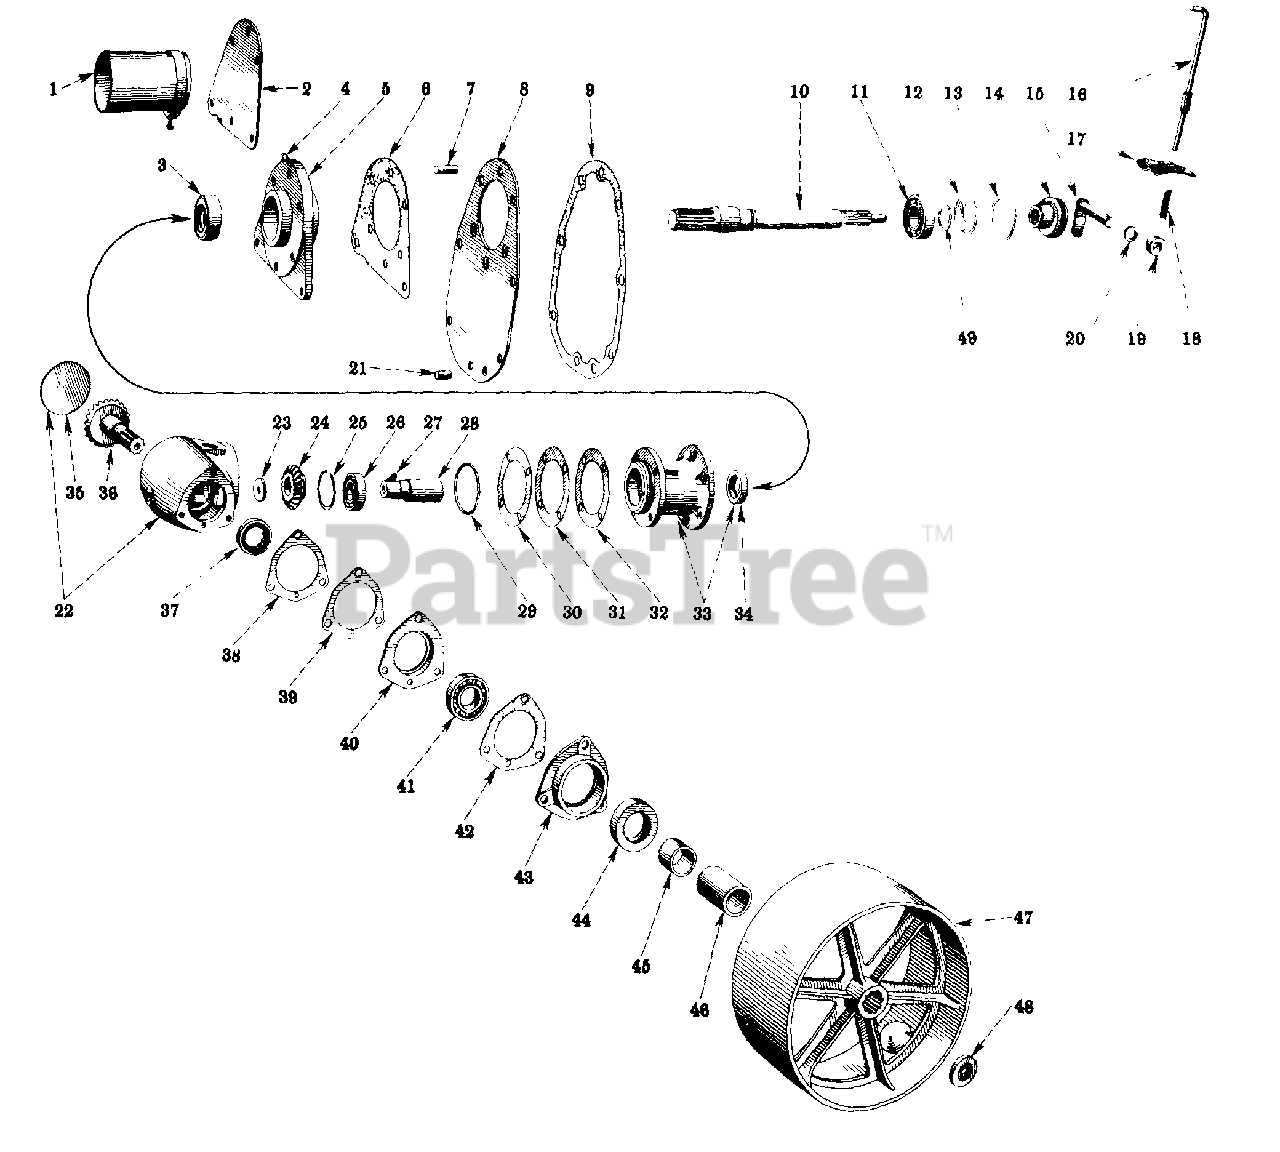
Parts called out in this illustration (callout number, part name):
1	GUARD ASSY, POWER TAKE OFF SHAFT
2	COVER, POWER TAKE-OFF ADAPTER
3	SEAL, POWER TAKE OFF SHAFT OIL
4	FITTING, 3/16 65 DEG. ANGLE DRIVE TYPE LUBRICATION
5	RETAINER ASSY. POWER TAKE-OFF SHAFT OIL SEAL AND BEARING
6	GASKET, POWER TAKE-OFF ADAPTER COVER
7	DOWEL, POWER TAKE-OFF ADAPTER UPPER
8	ADAPTER W/PRODUCT GRAPHIC, 539403-R1, POWER TAKE-OFF
9	GASKET POWER TAKE-OFF ADAPTER
10	SHAFT W/RING, 122791-R1 AND SHIELD, 351272-R2 PTO
11	BEARING, POWER TAKE-OFF SHAFT BALL
12	SHIELD, POWER TAKE-OFF BEARING GREASE
13	RING, POWER TAKE-OFF SHAFT BEARING SNAP
14	CLUTCH, POWER TAKE-OFF SHIFTER
15	LEVER AND SHAFT ASSY, POWER TAKE-OFF SHIFTER
16	ROD ASSY, POWER TAKE-OFF SHIFTER
17	GUIDE, POWER TAKE-OFF SHIFTER ROD
18	SPRING, POWER TAKE-OFF SHIFTER ROD
19	COLLAR, POWER TAKE-OFF SHIFTER LEVER
20	SEAL, POWER TAKE-OFF SHIFTER SHAFT
21	DOWEL, POWER TAKE-OFF ADAPTER LOWER
22	HOUSING ASSY, BELT PULLEY DRIVE
23	WASHER, BELT PULLY DRIVE PINION
24	PINION, BELT PULLEY DRIVE
25	RING, BELT PULLEY DRIVE HOUSING SUPPORT BEARING SNAP
26	BEARING, BELT PULLEY DRIVE HOUSING SUPPORT BALL
27	KEY, 3/16 X 3/4 WOODRUFF NO. 9
28	SLEEVE ASSY, BELT PULLY DRIVE PINION
29	O-RING, 2-3/4 X 3 X 1/8 BELT PULLEY DRIVE HOUSING
30	SHIM, BELT PULLEY DRIVE HOUSING
31	SHIM, BELT PULLEY DRIVE HOUSING
32	SHIM, BELT PULLEY DRIVE HOUSING
33	SUPPORT W/OIL SEAL, 19857D AND BREATHER, 355120-R91
34	SEAL, BELT PULLEY DRIVE HOUSING SUPPORT OIL
35	PLUG 3-1/4 IN. DIAMETER EXPANSION
36	SHAFT, BELT PULLEY DRIVE
37	BEARING, BELT PULLEY DRIVE SHAFT INNER
38	SHIM, BELT PULLEY DRIVE SHAFT BEARING CAGE
39	SHIM, BELT PULLEY DRIVE SHAFT BEARING CAGE
40	CAGE, BELT PULLEY DRIVE SHAFT BEARING
41	BEARING, BELT PULLEY DRIVE SHAFT OUTER
42	GASKET, BELT PULLEY DRIVE SHAFT OIL SEAL RETAINER
43	RETAINER W/OIL SEAL, 351276-R91 BELT PULLEY DRIVE SHAFT
44	SEAL, BELT PULLEY DRIVE SHAFT OIL
45	SPACER, BELT PULLEY
46	SPACER, BELT PULLEY DRIVE SHAFT
47	PULLEY, BELT 9 IN. DIA. X 4-3/4 IN. FACE
47	PULLEY, BELT 7-5/8 IN. DIA. X 4-3/4 IN. FACE
47	PULLEY, BELT 6 IN. DIA. X 4-3/4 IN. FACE
48	WASHER, BELT PULLEY DRIVE SHAFT
49	RING, POWER TAKE-OFF BEARING SNAP
